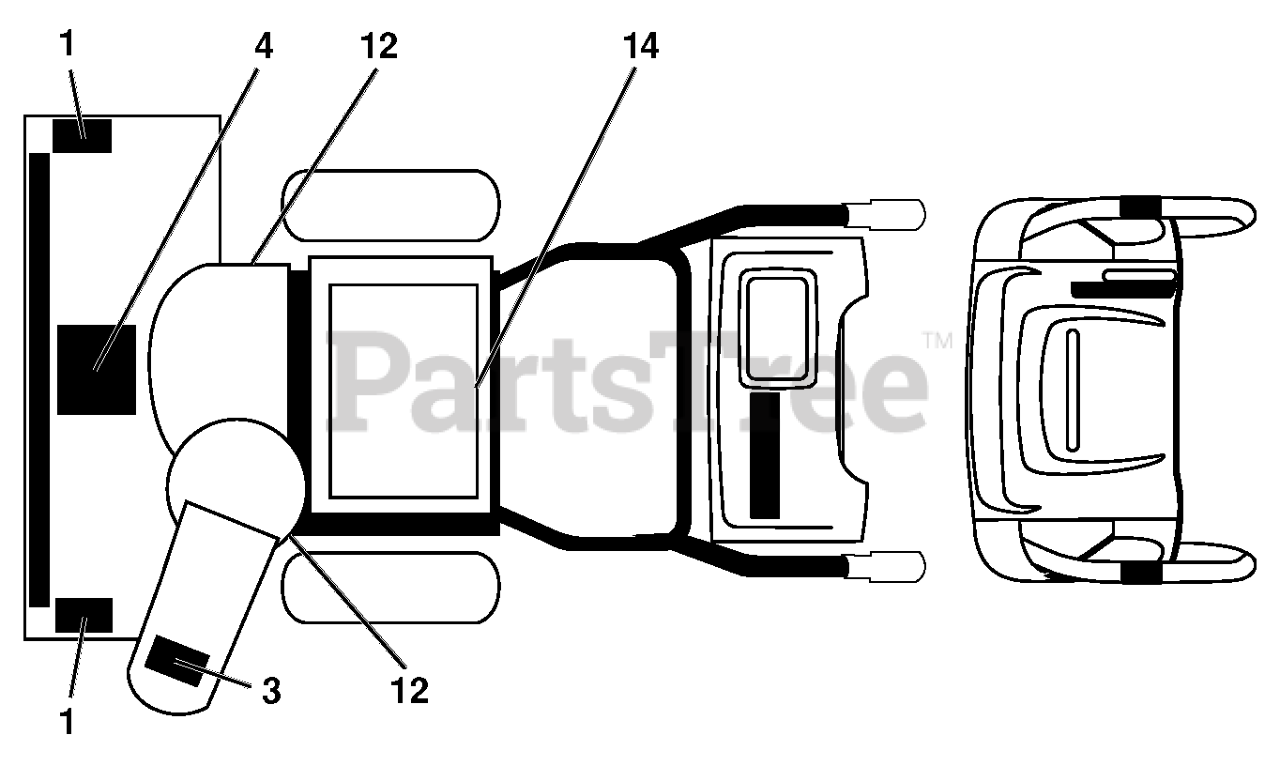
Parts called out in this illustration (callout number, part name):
1	DECAL.AUGER.SAFETY.
3	DECAL.CHUTE.SAFETY.
4	DECAL.AUGER."
12	DECAL.BELT.GUARD.
14	DECAL.FENDER
